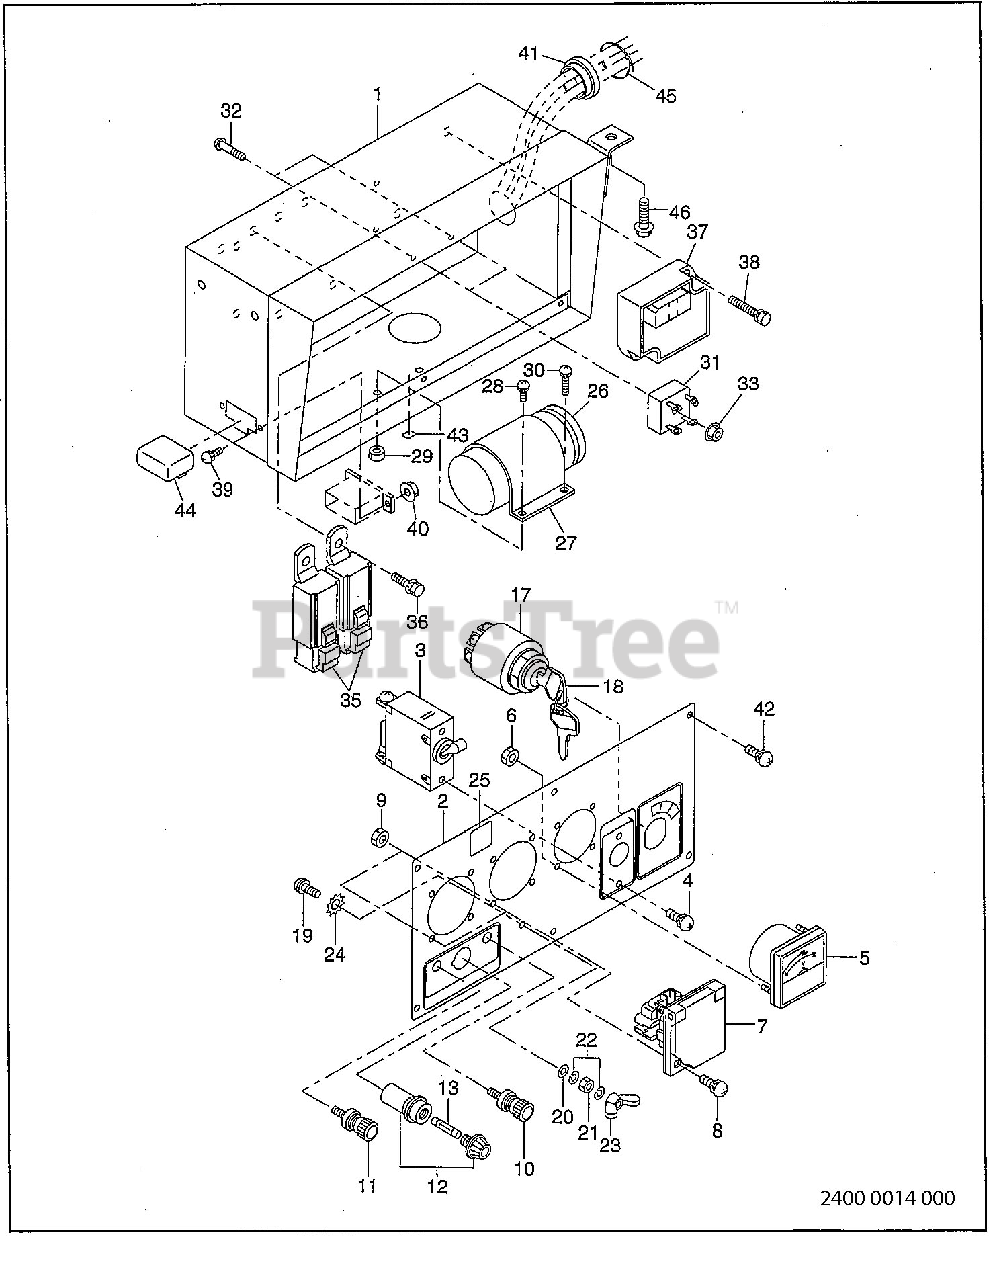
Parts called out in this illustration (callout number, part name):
1	CONTROL BOX ASSY
2	CONTROL PANEL AS'Y
2	CONTROL PANEL ASSY
3	CIRCUIT BREAKER (12A)
4	SCREW and WASHER ASSY
5	AC VOLT METER ASSY
7	AC RECEPTACLE (250V-16A)
8	SCREW and WASHER ASSY
10	TERMINAL BOLT (RED)
11	TERMINAL BOLT (BLACK)
12	FUSE HOLDER (250V-10A)
17	SWITCH
19	SCREW and WASHER ASSY
23	WING NUT
25	LABEL (ELECTRIC SHOCK)
26	CONDENSER (300VAC-21uF)
27	CONDENSER BRACKET
28	SCREW and WASHER ASSY
30	SCREW and WASHER ASSY
32	SCREW and WASHER ASSY
35	RELAY (CA) ASSY
36	BOLT and WASHER ASSY
37	ECU (DYRM) ASSY
38	BOLT and WASHER ASSY
39	SCREW and WASHER ASSY
42	SCREW and WASHER ASSY
44	CONNECTOR CAP
